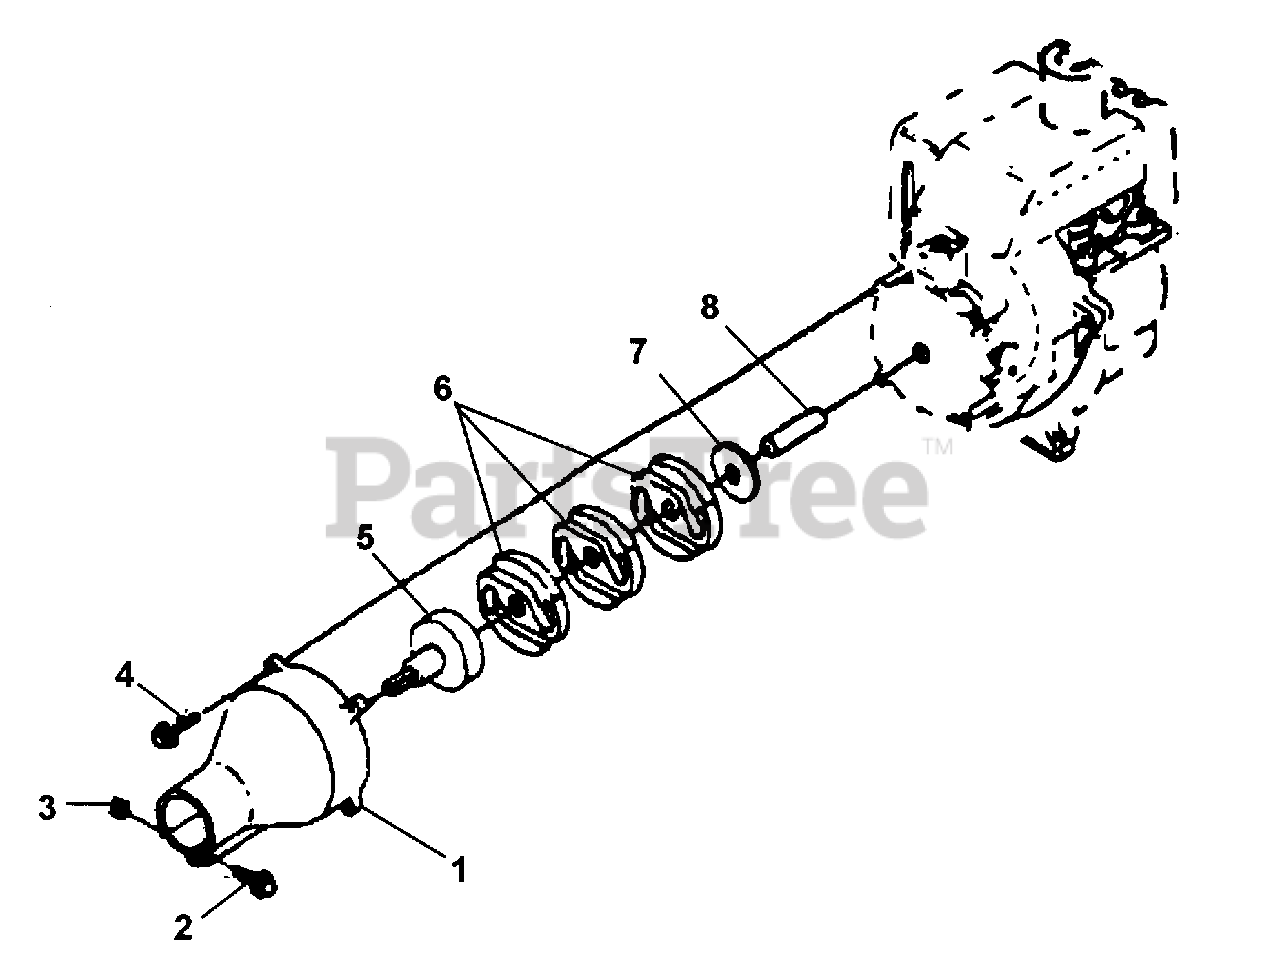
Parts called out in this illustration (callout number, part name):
1	CLUTCH CASE ASSY
2	SCREW, SEMS HEXHEAD 10-24 X 1 1/4"
3	NUT, HEX 10-24
4	SCREW, SEMS HEXHEAD 10-24 X 7/8"
5	DRUM & CONNECTOR
7	WASHER, CLUTCH
8	SPACER
